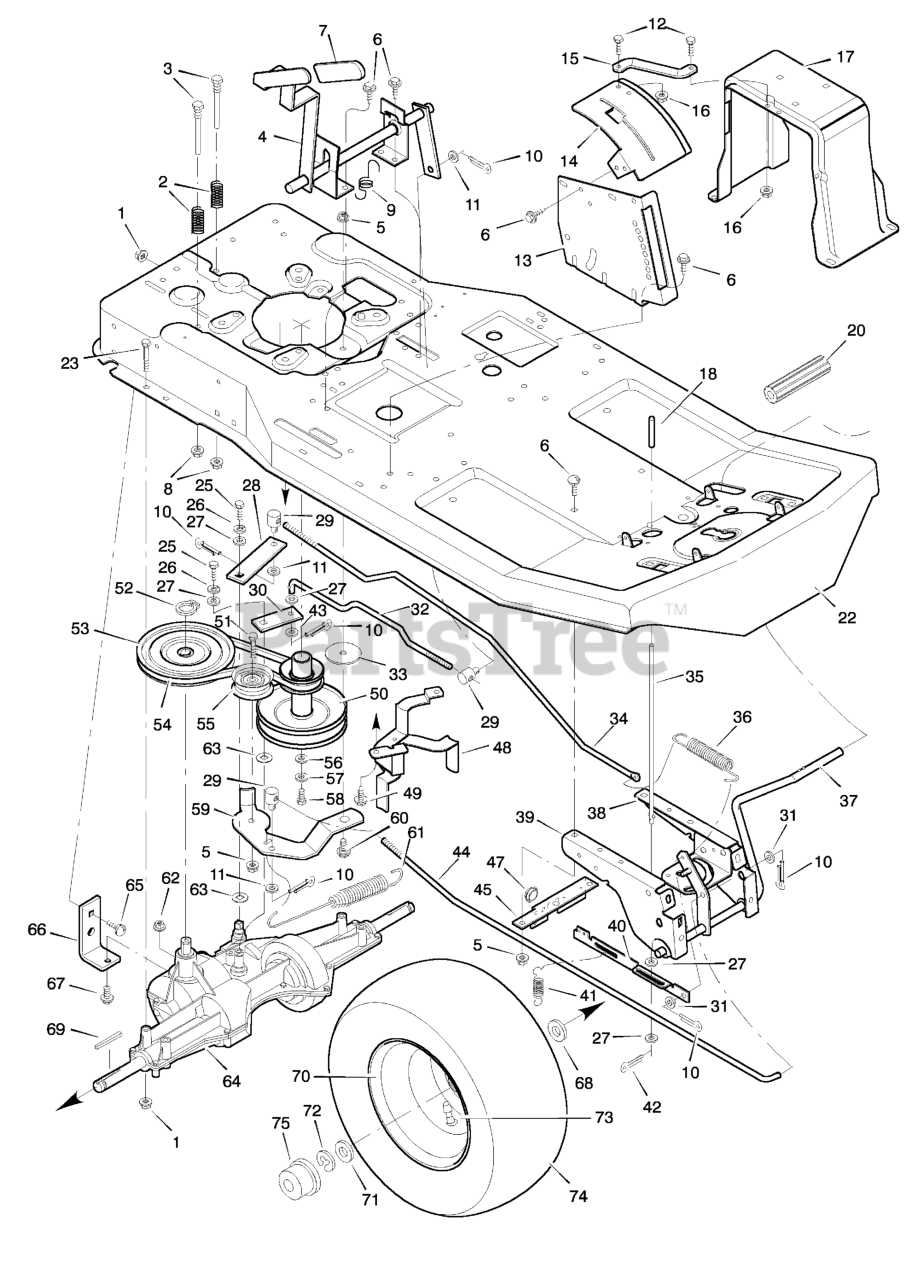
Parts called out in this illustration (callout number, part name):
1	Locknut, Flange
2	Spring, Compression
3	Guide, Belt
4	Shifter Assembly
5	Locknut, Flange
7	Grip, Shift Lever
8	Hex Nut
9	Spring, Extension
10	Pin, Cotter
11	Washer
12	Bolt, Hex
13	Plate, Index
14	Gate, Shift
15	Brace, Shift Gate
16	Locknut, Flange
17	Support, Seat
18	Grip, Parking Brake
20	Pedal, Rubber
22	Frame Assembly
23	Bolt, Hex
25	Bolt, Hex
26	Lockwasher
28	Yoke, Brake
29	Nut, Adjusting
30	Yoke, Shift
31	Washer
32	Rod, Shift
33	Washer, Hardened
34	Rod, Brake
35	Rod, Parking Brake
36	Spring, Extension
37	Lever, Pedal
38	Plate, Left Suspension
39	Plate, Right Suspension
40	Link, Parking Brake
41	Spring, Extension
42	Pin, Cotter
44	Rod, Clutch
45	Stop, Parking Brake
47	Grommet
48	Guide, Belt
50	Pulley Assembly, Stack
51	Bolt, Hex
52	Ring, Retainer
53	Pulley, Drive
54	Belt, Motion Drive
55	Pulley, Idler
57	Lockwasher
58	Bolt, Hex
59	Bracket, Idler
60	Bolt, Shoulder
61	Spring, Extension
62	Locknut, Hex
64	Transaxle, Dana Model 4450-1 **
65	Bolt, Carriage
66	Bracket, Transaxle
67	Bolt, Hex
69	Key, Square
70	Wheel & Tire Assembly
72	E- Ring
73	Valve Stem
74	Tire *
75	Hub Cap
